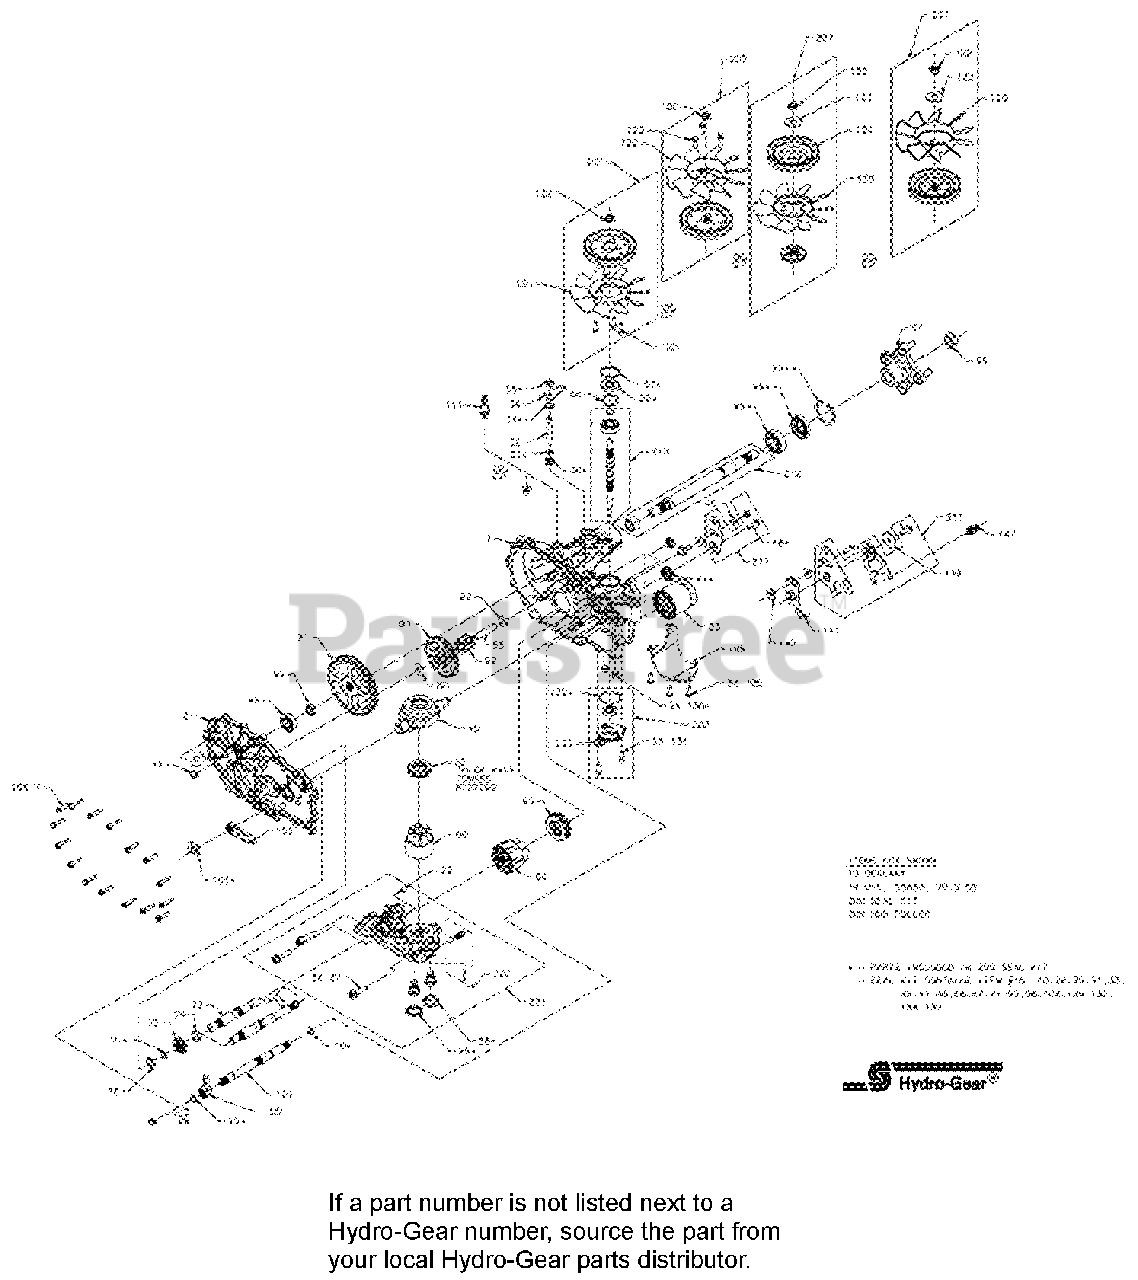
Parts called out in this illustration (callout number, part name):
1	KIT, HOUSING, MAIN, LH, CHRG, CNTL
2	KIT, COVER, SIDE, LH
11	PLUG, STEEL (WITH SEAL)
13	SEALANT TUBE 10.1OZ.
22	PLATE, BYPASS
23	FILTER, HYDRO-GEAR 2800 TRANS
27	HFHCS 3/8-16 x 1.5 (PATCH)
30	SEAL, LIP .375X.75X.25
31	RING. RETAINING
32	ROD, BYPASS
33	RING, RET .750
34	ARM, BYPASS
35	RING, RTNG .
40	TRUNNION, SWASHPLATE
41	SEAL, LIP 18X32X7
45	WASHER
46	TWHCS 5/16-24 X 1.00
55	WASHER 1.23X1.56X.04
56	SEAL, LIP 17X40X7
57	RING, RET 1.56 INT
60	BEARING, THRUST
65	BEARING. THRUST 30 X 52 X 13
69	ASSY, BLOCK 7 PISTON
70	WASHER .63X1.0X.05
71	RING, RET 62 EXT
73	SHAFT, MOTOR
74	WASHER .71 X 1.16 X .04
80	WASHER .5X1.0X.032
83	JACK SHAFT (PIN)
90	RING, RETAINING
95	BEARING, BALL 25.4 X 52 X 15
96	SEAL, LIP
97	KIT, HUB, 4 BOLT
99	NUT, HEX, LOCK 3/4-16
100	PAWL, BRAKE
101	SHAFT, BRAKE
102	ARM, BRAKE
103	CLIP,BRAKE ARM HYDROGEAR 52027
105	HFHCS 1/4-20X.75
106	GUARD, FILTER, LH
111	FITTING, STR 9/16-18 SAE .5 BARB
120	FAN, HYDROGEAR 52576
122	NUT, HEX 1/2-20 PATCH
123	HFHCS 1/4-20X.875
130	TUBE, CONNECTING
131	GEROTOR
132	O-RING HYDROGEAR 52250
133	COVER, CHARGE PUMP
134	HFHCS 1/4-20X.75
141	ARM, NEUTRAL RIGHT
142	SHCS 5/16-24X1 PATCH
146	WASHER
147	SPRING, HYDROGEAR P/N 51833
200	KIT, SEAL
201	KIT, CENTER SECTION, LH, CHRG
202	KIT, CHARGE RELIEF
203	KIT, CHARGE PUMP
207	KIT, FAN & PULLEY
209	HUB PULLER 4 BLT HYDGEAR 71459
210	INPUT SHAFT 2800 HYDGEAR 71442
211	KIT, RTN, CCW
212	KIT, SHAFT, AXLE
